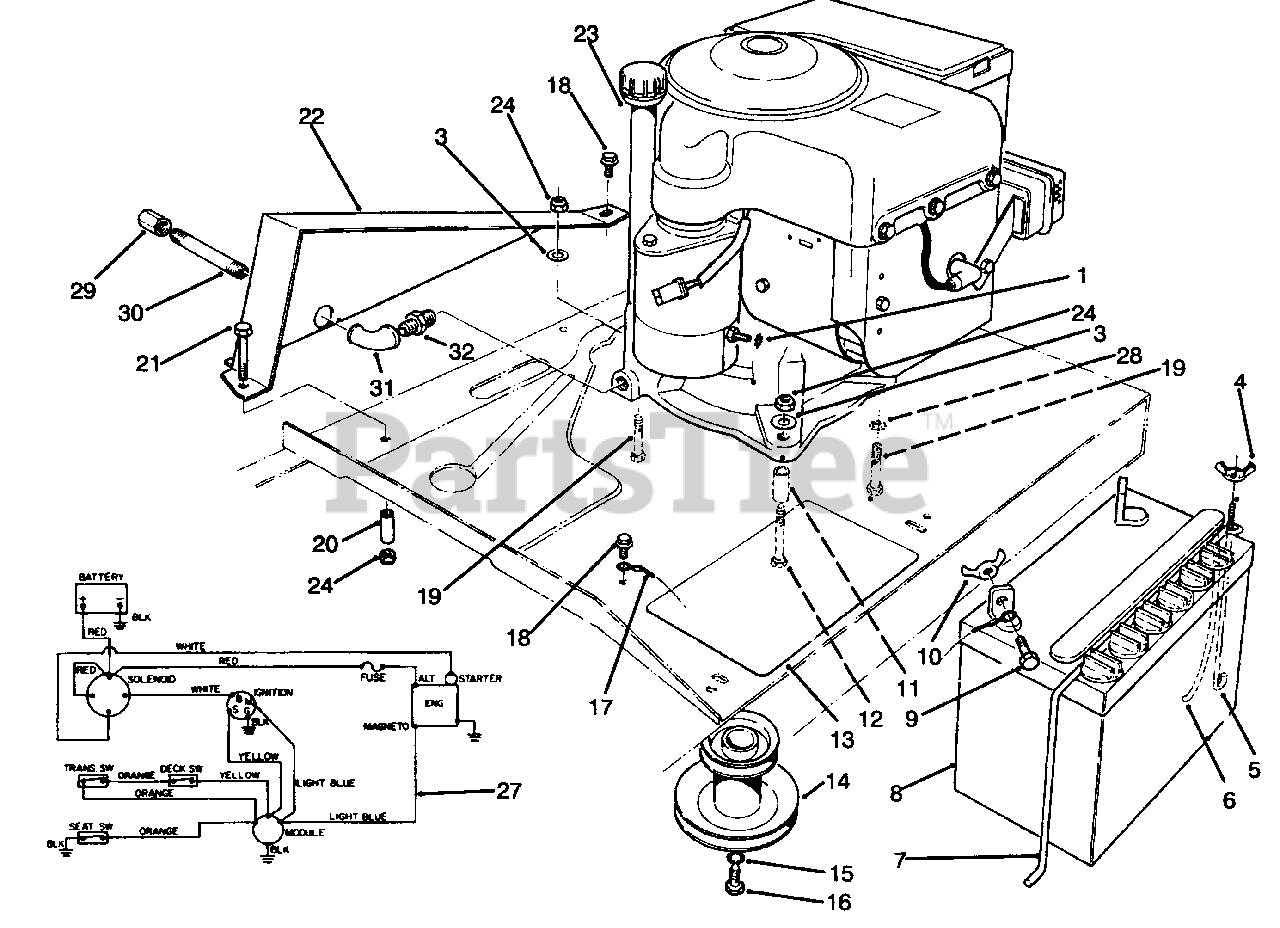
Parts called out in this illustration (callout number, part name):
1	Washer-Lock, Int. Tooth
3	Washer-Flat
5	Post-Hold Down, Battery
6	Tube-Drain
7	Hold Down-Battery
8	Battery 12V
9	Screw-Cap Hex. Hd.
12	Screw-Cap Hex. Hd.
13	Pad-Anti-Skid
14	Pulley-Engine
15	Washer-Flat
16	Screw-Cap Hex. Hd.
17	Assembly-Wire Battery to Ground
18	Screw -Self Tapping
19	Screw-Cap Hex. Hd.
20	Guide-Belt
21	Screw-Cap Hex. Hd.
22	Guard-Chain
23	Engine-8 H.P. B & S
24	Nut-Lock
27	Harness-Wire
28	Washer-Lock
29	Cap-Pipe
30	Nipple-Pipe
31	Elbow-Street
32	Reducer
